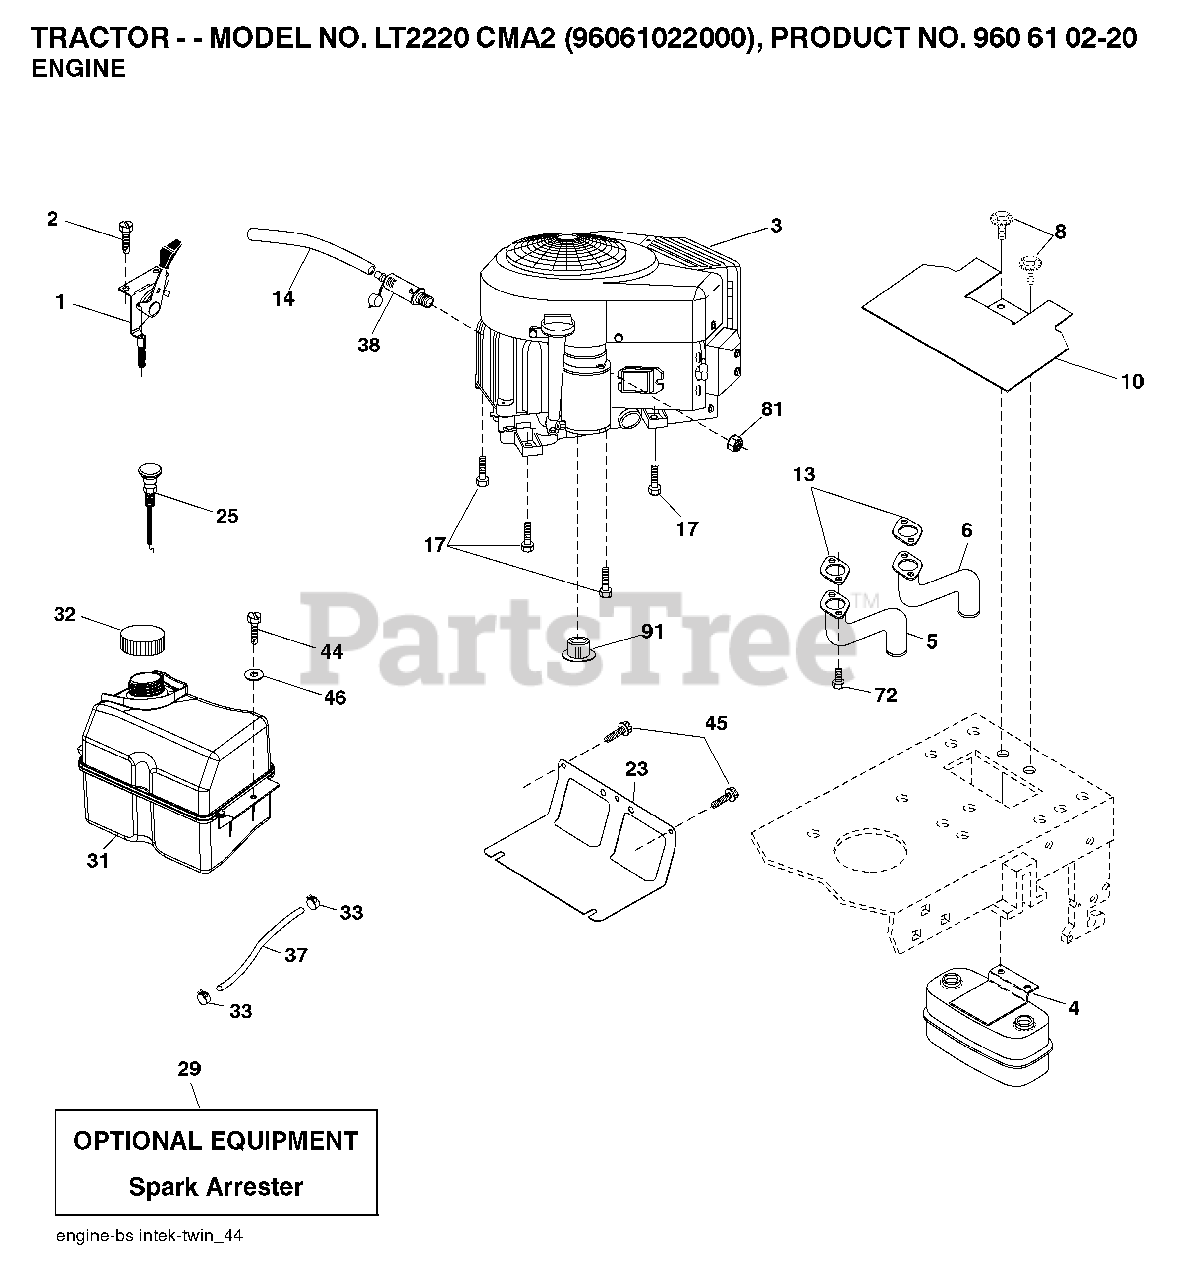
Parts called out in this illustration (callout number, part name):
1	THROTTLE CABLE
2	SCREW
4	MUFFLER.TWIN.CYL.LOW.TONE
5	EXHAUST TUBE RH
6	TUBE MANIFOLD LH
8	BOLT, 5/16-18 X 1 3/4
10	RP SHIELD HEAT MUFFLER
13	GASKET.MUFFLER
14	TUBE, DRAIN OIL ASM.
17	SCREW.3/8-16
23	SHEILD.BROWNING.DBR.GUARD
25	CONTROL CHOKE
29	ARRESTER SPARK (OPTIONAL)
31	FUEL TANK FRT 2 GAL.
32	FUEL CAP
33	HOSE CLAMP
37	LINE.FUEL.20
38	PLUG DRAIN OIL EASY
44	SCREW HEXWSHR 1/4-20X3/4
45	SCREW, 3/8-16X3/4
72	SCREW.SOCKET.HEAD.5/16-18
81	NUT
